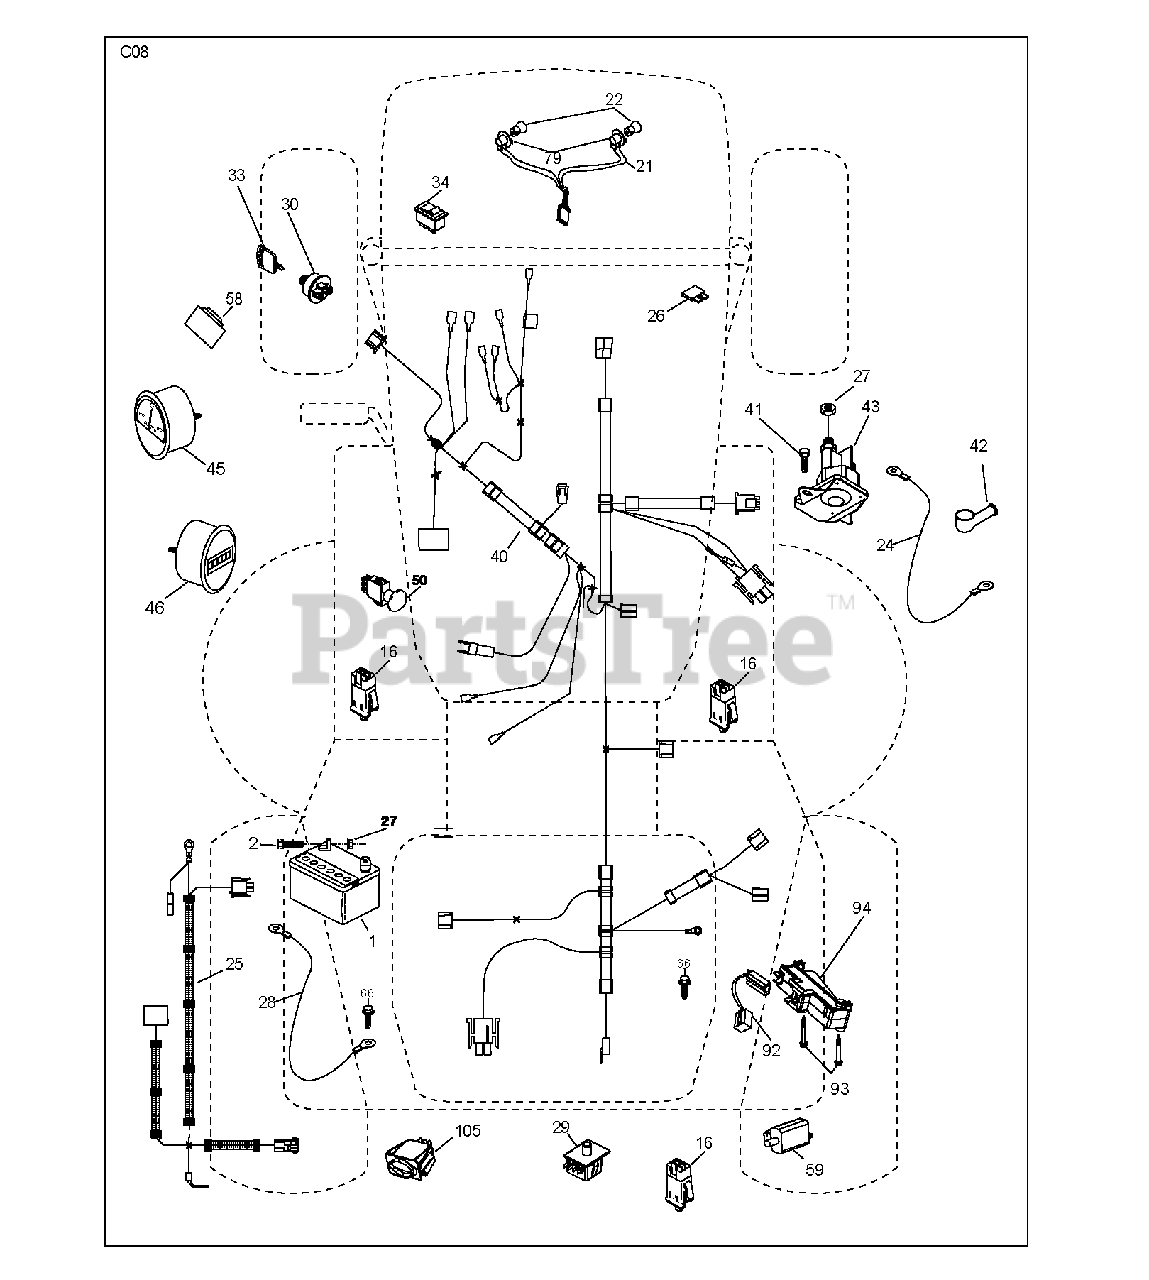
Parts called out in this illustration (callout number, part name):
1	REPL BY 532 12 38-99
16	SWITCH INTERLOOK PUSH-IN
21	HARNESS.W/LIGHT SOCKET
22	LIGHTBULB
25	CABLE BATTERY 6 GA. 11" RED
26	FUSE 20AMP
27	NUT
28	CABLE GROUND
29	SWITCH.SEAT.DP W/RAMPS
30	SWITCH.IGN.DELTA.W.LGH.ROS
33	KEY.CHAIN.BLISTER.PACK.GEN.INT
34	SWITCH LT
42	TERMINAL COVER
43	SOLENOID.W/BRASS.PLUNG
50	PTO SWITCH
58	BUZZER
79	BULB HOLDER ASM.
92	HARNESS.PIGTAIL.CONSLE
93	SCREW.PLASTITE
94	MODULE.REVERSE.ROS
